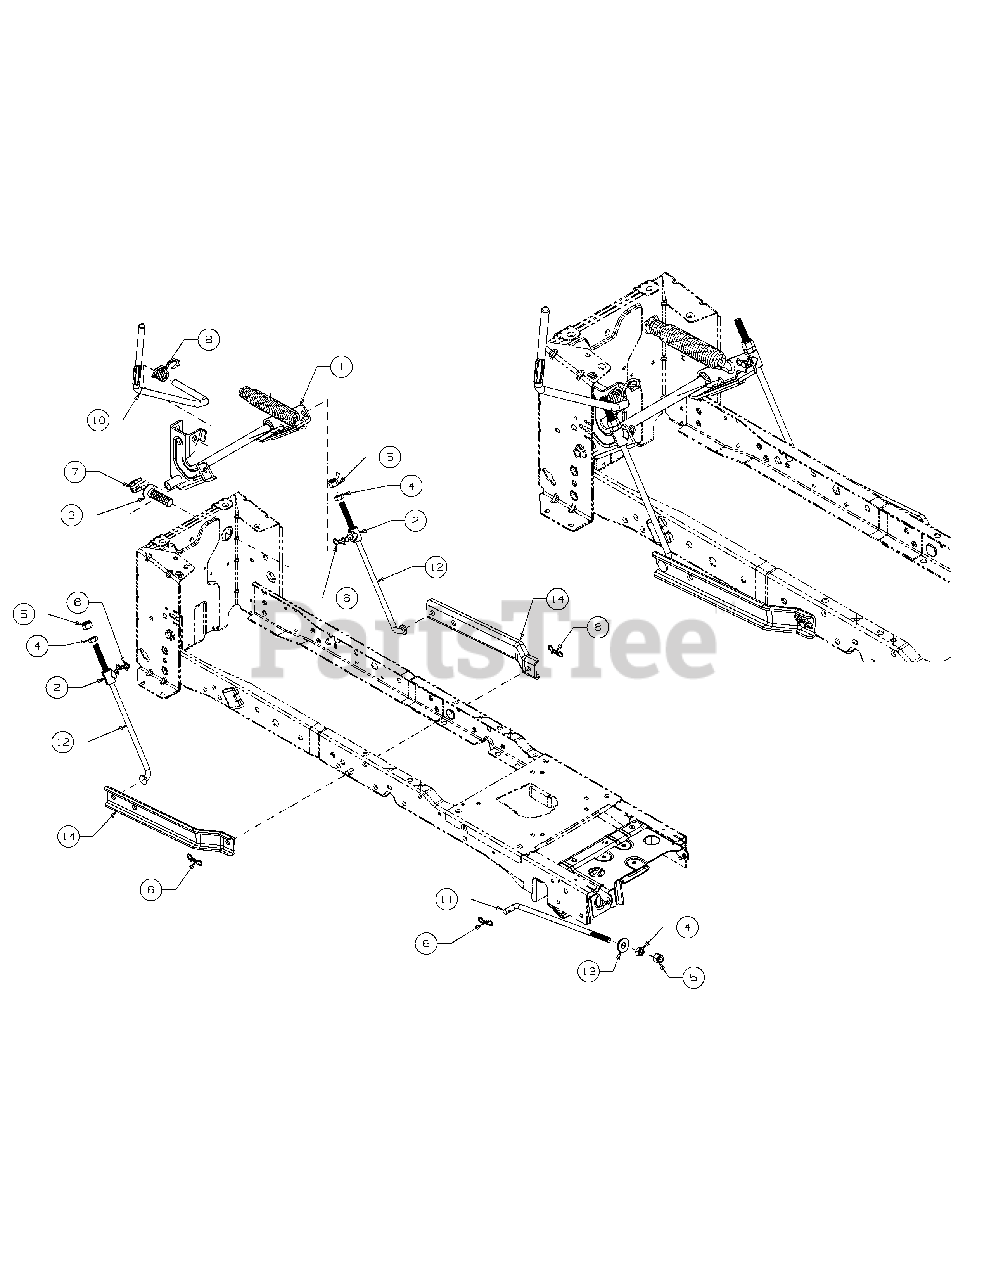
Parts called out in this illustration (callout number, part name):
1	Shift Asm:Lift:Deck
2	Ferrule-Lift Rod
3	Insert-Lift Spring
4	Nut:Jam:1/2-13:Gr5
5	Nut-Hex Lock Nylon
6	Pin-Bow Tie Cotter
7	Spacer-Lift Shaft
8	Spring-Torsn Lift
9	Grease:Alvania Ep 2
10	Handle-Deck Lift
11	Rod-Deck Frnt Lift
12	Rod-Adj Lift
13	Lift Pivot Cup
